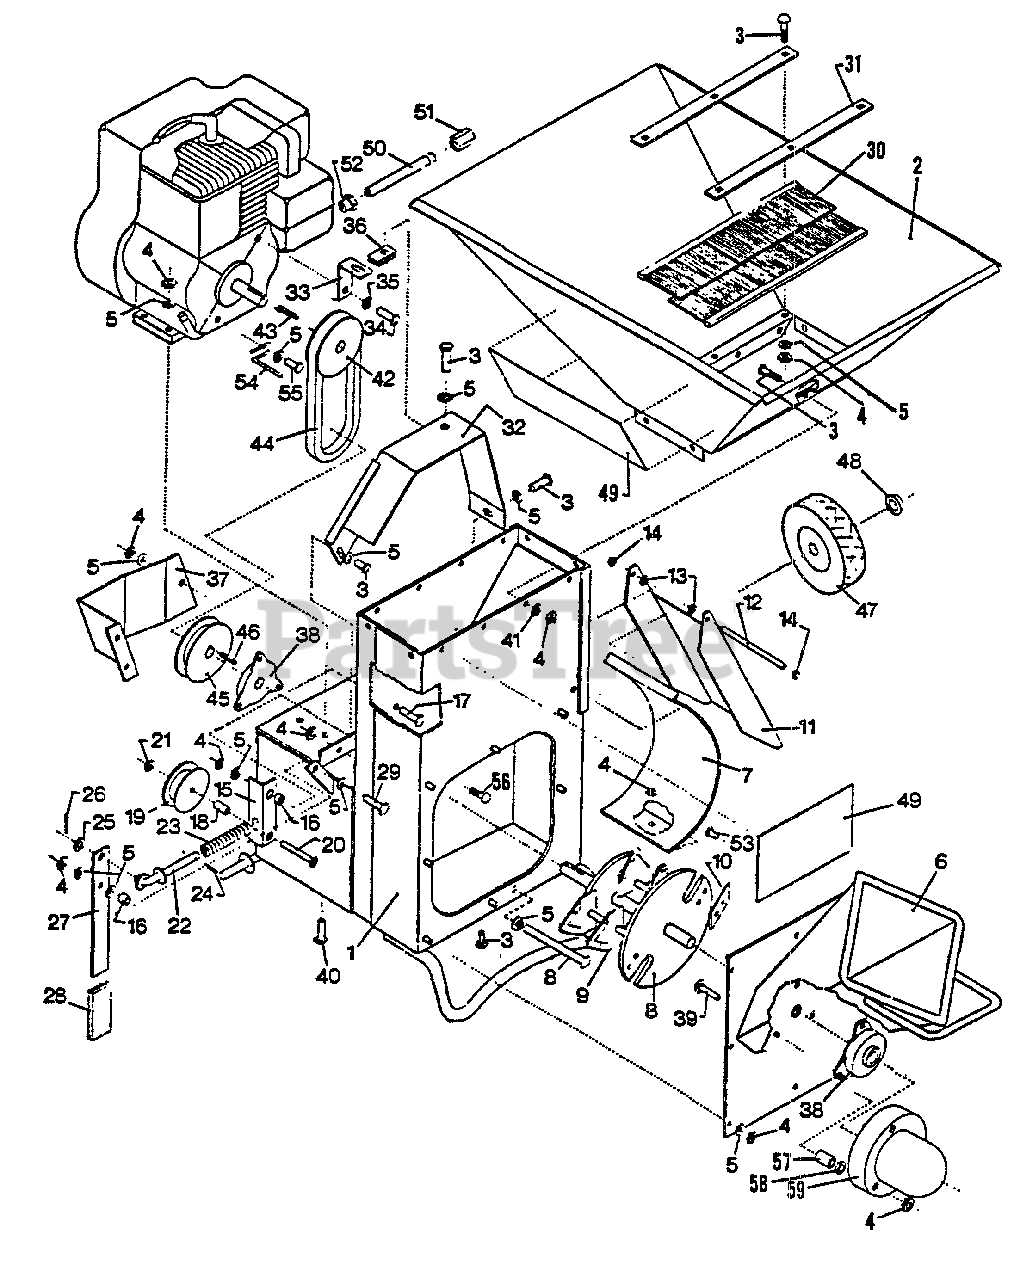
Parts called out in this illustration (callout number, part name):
7	GRATES
7	INSTRUCTIONS, SHREDDER KIT
16	SPACER, IDLER PIVOT
16	ANGLE, HONDA GUARD SUPPORT - 8 HP
16	BEARING, CAST FLANGE (8000 R ONLY)
49	LABEL - MODEL SH-3000
49	LABEL - MODEL SH-5000
49	LABEL - MODEL SH-8000E
49	LABEL - MODEL SH-8000 E
49	LABEL - MODEL SH-8000 I.C.
49	LABEL - MODEL SH-8000 R
